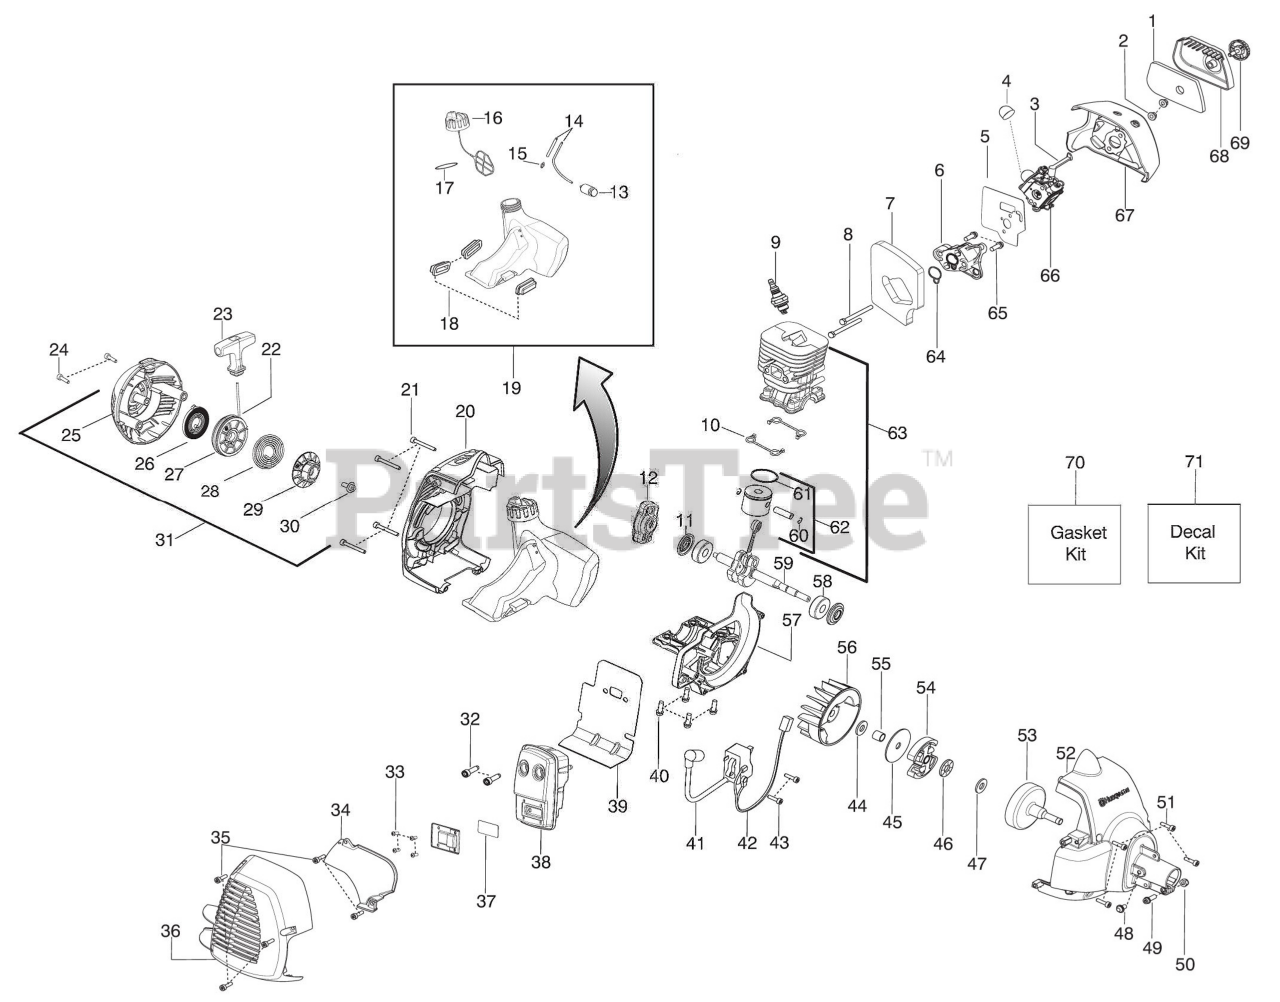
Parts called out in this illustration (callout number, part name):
2	Nut-Carb. Screw
3	Lever - Choke
4	Bulb-Purge
5	Kit-Carb. Gasket
6	Adaptor-Carb.
7	Foam-Gasket
9	Plug-Spark
10	Seal-Cylinder
11	Seal-Crankshaft
12	Assy-Starter Pawl
13	Assy-Fuel Filter
14	Kit-Fuel Line
15	Fitting-Fuel Line
16	Assy-Cap w/ret.
17	O-Ring-Fuel Cap
18	Isolator-Fuel Tank
19	Kit-Fuel Tank Assy.
20	Shroud-Rear
22	Kit-Rope
23	Handle-Starter
25	Starter Hsg. w/eyelet
26	Kit-Spring
27	Kit-Starter Pulley
28	Spring - Driver
29	Pulley-Driver
31	Assy-Starter Hsg.
32	Bolt-Muffler
33	Screw
34	Shield-Heat
36	Guard-Muffler
37	Kit-Spark
38	Kit-Muffler
39	Gasket-Paper Met.
42	Assy-Leadwire
45	Washer-Clutch
46	Bearing - Thrust
47	Washer - Thrust
52	Assy-Fan Housing
53	Assy-Clutch Drum
54	Assy-Clutch
57	Crankcase-cast
59	Assy.-Crankshaft
60	Retainer-Piston Pin
61	Ring-Piston
62	Kit-Piston
63	Kit-Cyl./Piston
64	Seal-adaptor
66	Kit-Carb.
67	Airbox
68	Cover-Air Box
70	Kit-Gasket
